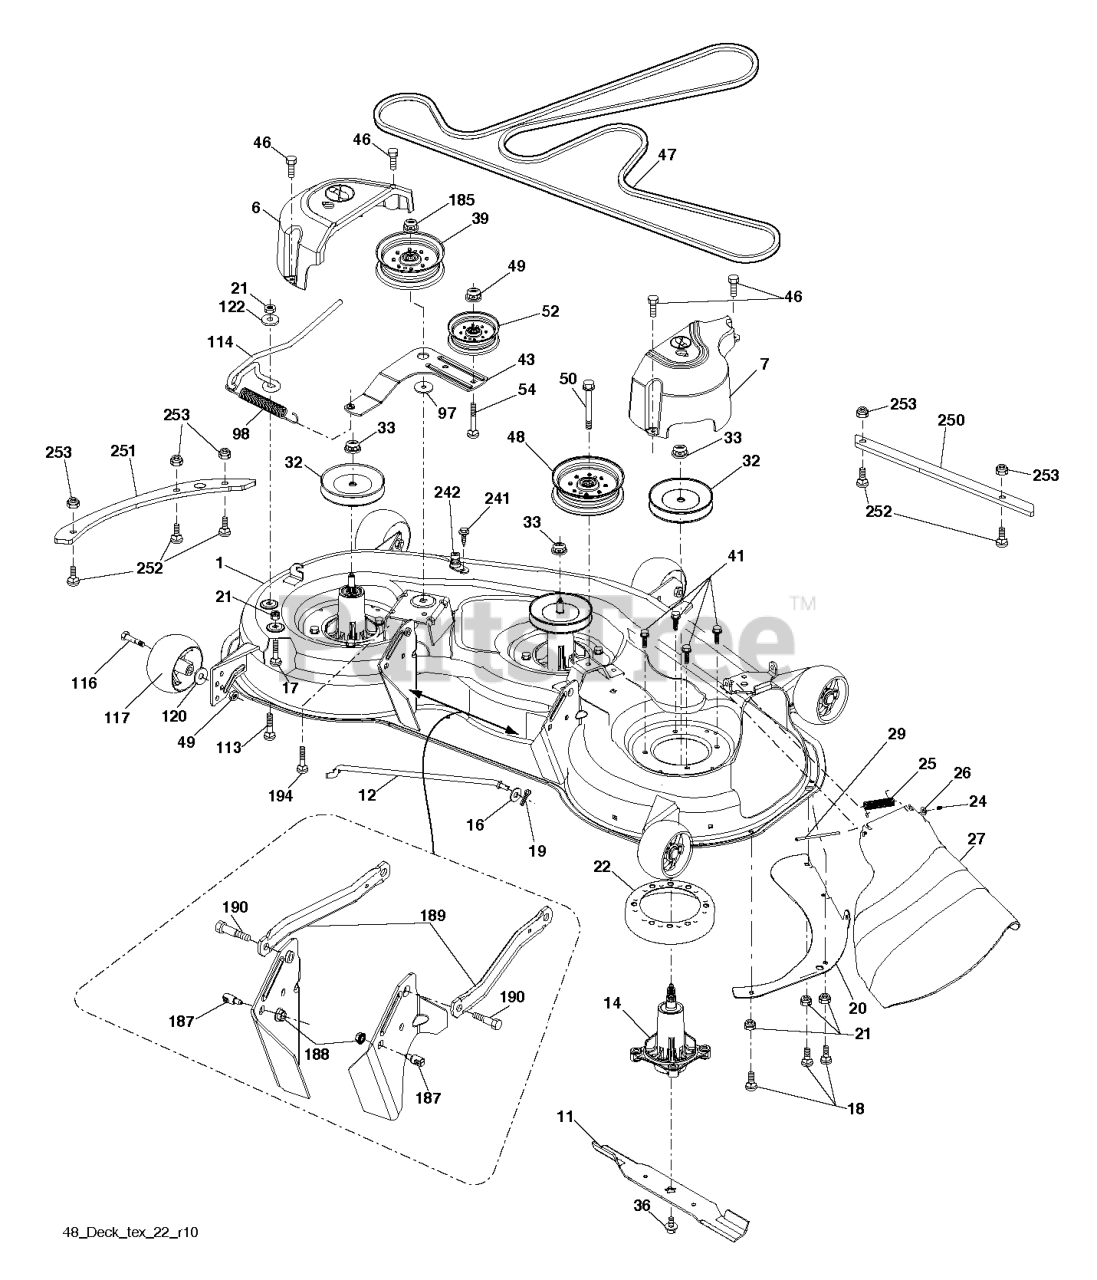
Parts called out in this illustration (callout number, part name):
1	DECK.SVC.48"
6	COVER.MANDREL.LH.48"(2 2)
7	COVER.RH.MANDREL
11	48" HI-LIFT BLADE
12	ROD.ANTI.SWAY.48/54"K4
13	SHAFT ASSY, MANDREL SHAFT
14	RP.HOUSING.MANDREL.4PT.
15	BEARING.MANDREL.TOP.EXTENDED
16	WASHER
17	BOLT.CARR.5/16-18X5/8.SHORT
18	BOLT
19	PIN.COTTER.5/16.BOW TI
20	BAFFLE, VORTEX MWR
21	LOCKNUT
22	STRIPPER.MANDREL.ROUND.BLACK
24	CAP-SLEEVE LT
25	SPRING, TORSION
26	NUT PUSH M
27	DEFLECTOR SUBS TO 532 180655
29	ROD.HINGE
32	PULLEY MANDREL
33	NUT.FLANGE.LOCK.TOP
36	SCREW.SEMS.7/16-20X1.HEX.HEAD
39	RB PULLEY.IDLER.4.50/HUB SPEC
41	BOLT.HEX.WASHR.HED.313-18X1.19
43	ARM.IDLER
46	SCREW.1/4-20X5/8
47	BELT.DRIVE.DECK
48	PULLEY.IDLER.2006
49	NUT LOCK FLG 3/8-16 UNC
50	SCREW TT 3/8-16X2-1/4 UNC
52	PULLEY.IDLER.48"PRIMARY
54	BOLT.3/8-16X1.50
98	SPRING, DECK DRIVE
113	RHSSNB 5/16C X 1.0
114	ROD.TENSION.RELIEF.TEX (2 2)
116	BOLT.SHOULDER.3/8-16X3-5/8.
117	WHEEL.GAUGE.RALLY
120	WASHER
122	BUSHING.RELIEF.TENSION
185	NUT.LOCK.FLANGE.7/16
187	STUD.FASTNER.W/ANTI-ROTATE
188	NUT LOCK HEX FLANGE 5/16-18
189	ARM.SUSPENSION.MOWER
190	BOLT.SHOULDER
194	BOLT.HEX.WASHER.HEAD.7/16-24X
241	SCREW.TT.#10-32X.5.3/8.FLANGE
242	PORT.WASHOUT
250	PLATE.REIN.FRNT.BOLTON.48X431
251	PLATE.REIN.SIDE.BOLT.ON.48X431
252	RHSNB, 1/4-20 X 1, GR5
253	NUT T
